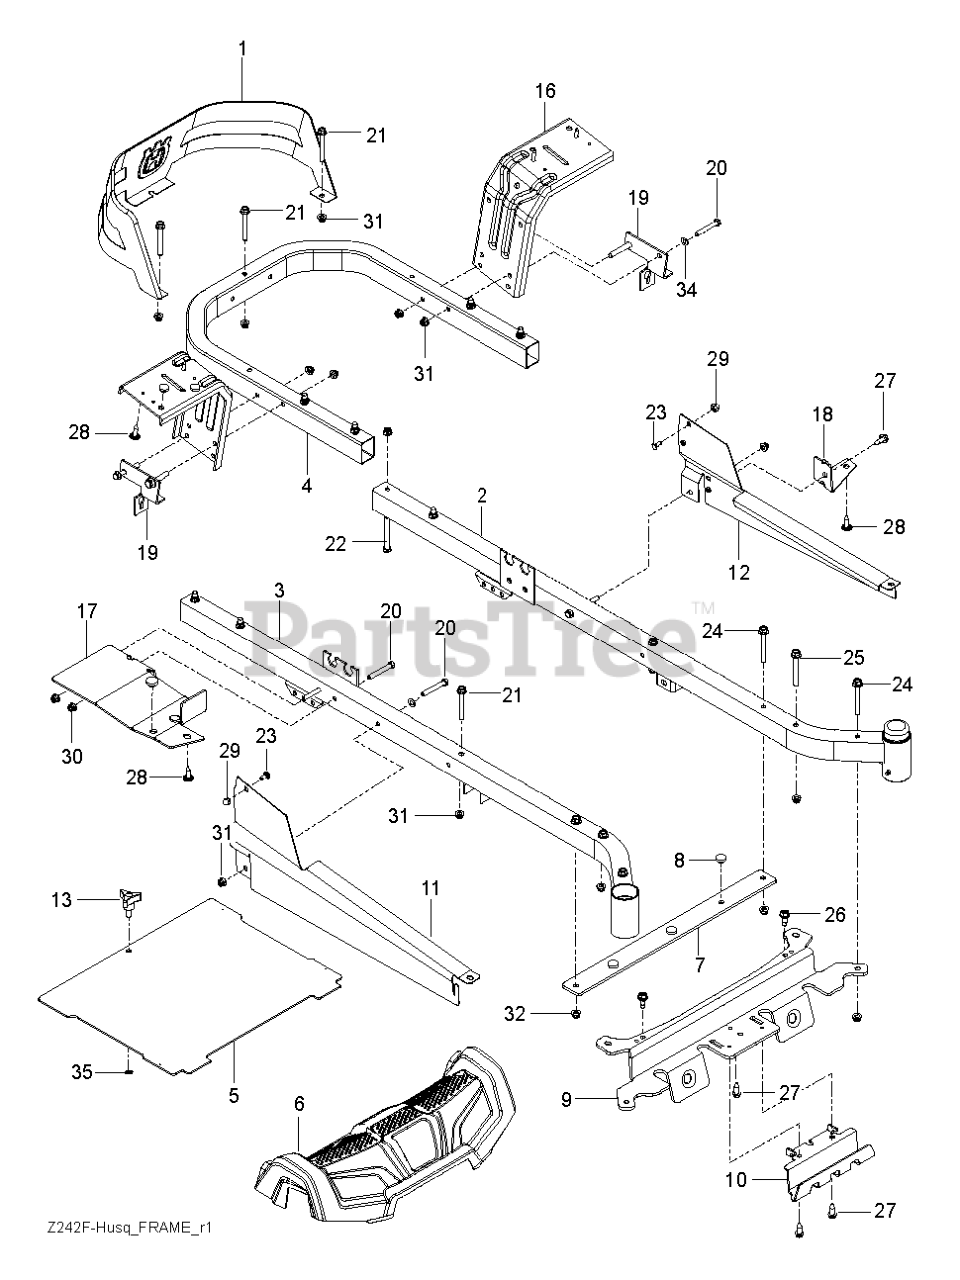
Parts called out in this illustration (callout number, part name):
1	GUARD.ENGINE.HUSQ.RZ.X498
2	FRAME.TUBE.RZ.MAIN.WELD.RH.ORG
3	FRAME.TUBE.RZ.MAIN.WELD.LH.ORG
4	TUBE.PNT.FRAME.RER.HUSQ.23".RZ
5	PLATE, FOOT W/DECALS RZ
6	COVER.FOOTREST.REFRESH.ASM
7	FOOTREST.PLATE.SUPPORT.X431
8	GROMMET.BUMPER
9	CROSS.PNT.MEMBER.BLK
10	SKID.PLATE.PNT.RZ.REF.SIVER
11	COVER.RAIL.RH.RZ.X668
12	COVER.RAIL.LH.RZ.X668
13	KNOB W/STUD
16	FENDER.SUPPORT.PNT.X431
17	SUPPORT.PNT.RH.CONSOLE.FRONT
18	SUPPORT.PNT.LH.CONSOLE.FRONT
19	BRKT ROD.BYPASS.EZT.X431
20	BOLT.FIN HEX 5/16-18UNC X2 1/4
21	BOLT HEX 5/16-18 GR 5
22	BOLT.HEX.FIN.3/8-16 X 3.GR5
23	BOLT.CARRIAGE.5/16-18.7/16
24	HHFS 3/8-16 X 3 GRD 5 ZD
25	BOLT SHOULDER,FLANGED,3/8-16X3
26	BOLT.5/16-18.THRD.ROLL.SHOULDR
27	BOLT.5/16HEX.WHS.HD
28	SCREW.#10 X 0.750.BOS
29	NUT ACORN,FLANGED,5/16-18
30	NUT LOCK HEX FLANGE 5/16-18
31	5/16-18 NYLOC FLANGE NUT
32	NUT 3/8-16 HEX FLG NYLOC ZD
34	WASHER
35	WASHER 5/16"
